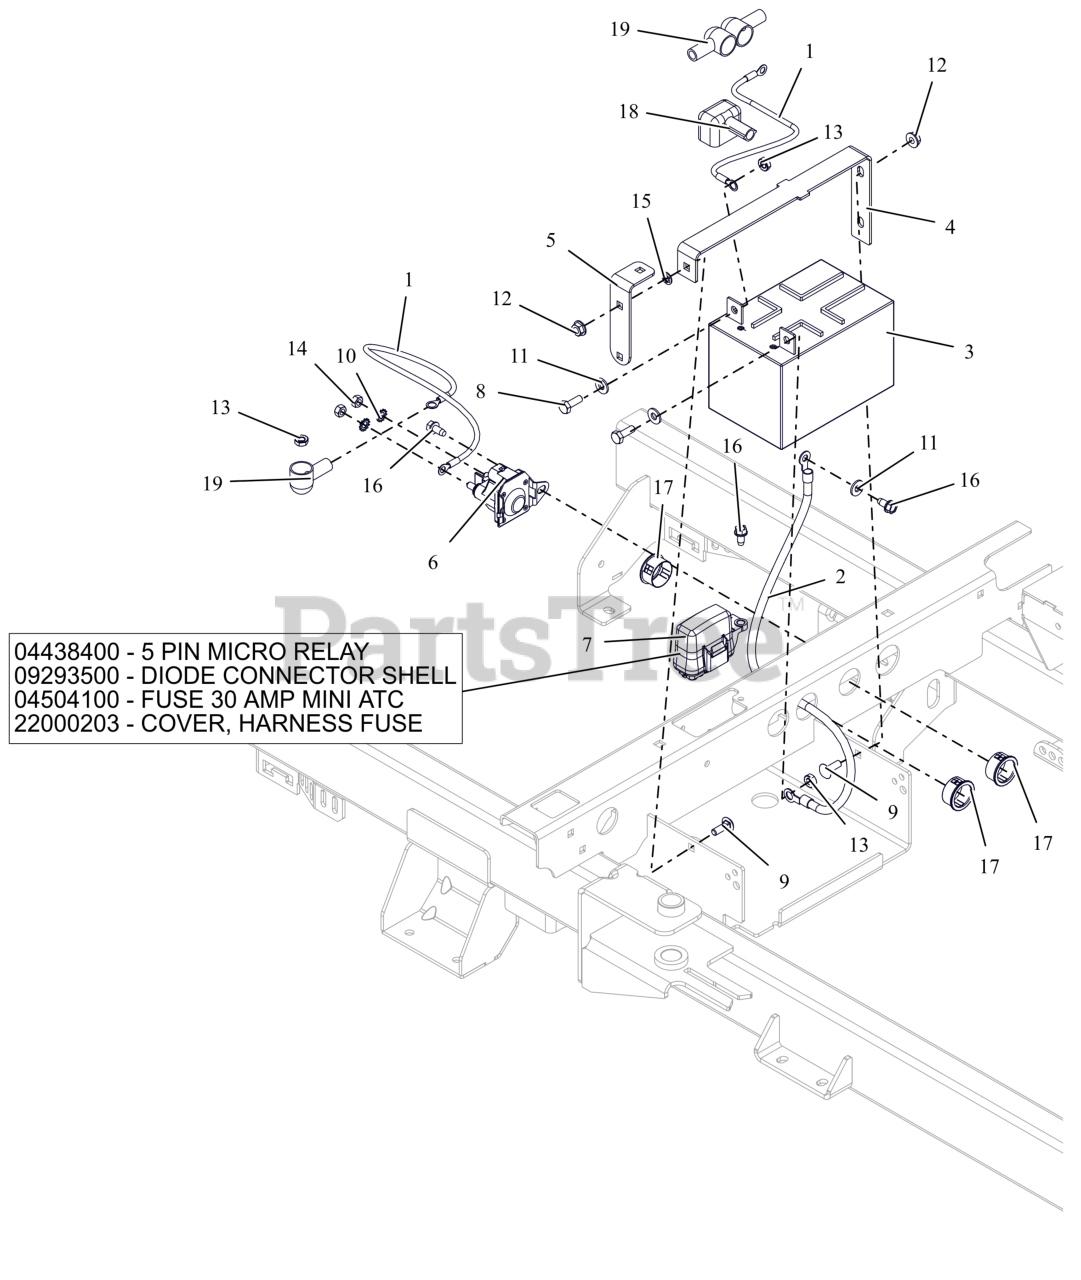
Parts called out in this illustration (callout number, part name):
1	CABLE,POS W/2 1/4 RING 15.0 LG
2	CABLE-NEGATIVE BATTERY 24.00"
3	BATTERY, 12V 12A-190CCA
4	BRKT, BATTERY HOLD-DOWN
5	BRKT, BATTERY HOLD DOWN
6	SOLENOID, STARTER (SEALED)
7	HARNESS, WIRE
7	RELAY,MICRO5 TERML W/RESISTOR
7	DIODE, CONNECTOR SHELL
7	FUSE,30 AMP MINI-ATC
7	COVER, FUSE
8	BLT, HEX .25-20X.75 G5 ZCC
9	BLT, RHSN .25-20X.750 G5 ZCC
10	WSHR,LK-EXT.262X.502X.026 ZCC
11	WSHR,FLT .281X.625X.065 ZCC
12	NUT-LK-TOP-FLG .250-20 GF ZCC
13	NUT-KEPS .250-20 ZCC
14	NUT-STD M6-1.0 ZCC
15	NUT-PUSH .25X.50 O.D.
16	SCR-TAP .25-20X.50 HWH ZCC
17	BSHG, PANEL SNAP .937X1.11X.56
18	INSULATOR
19	BOOT, EYELET TERMINAL
